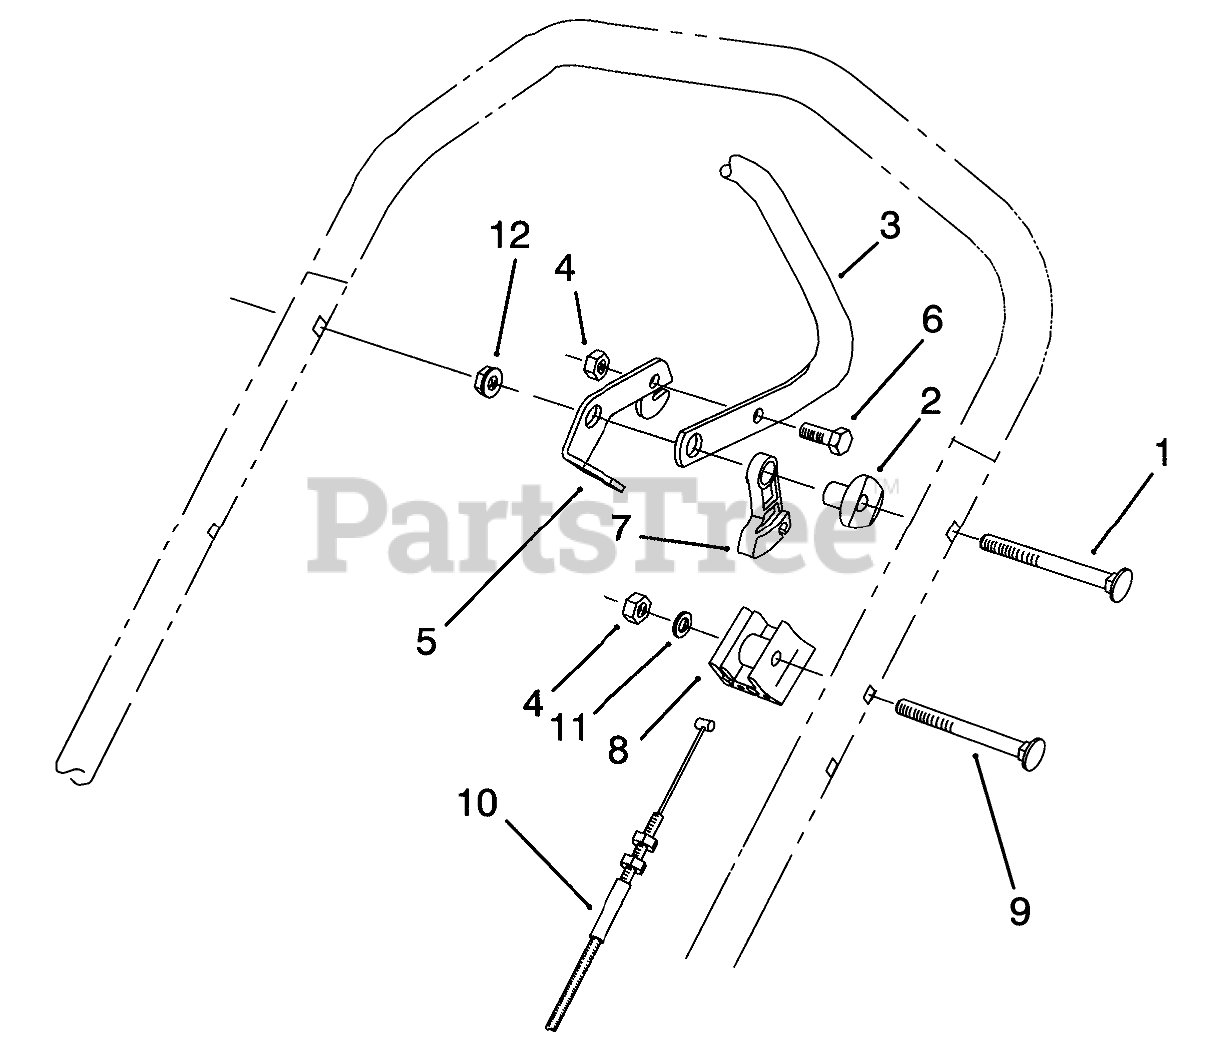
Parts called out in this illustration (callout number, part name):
1	SCREW-HANDLE
2	SPACER-SUPPORT
3	Bar-Control
4	NUT-LOCK, NI
5	LEVER-CONTROL
6	SCREW-HH
7	LEVER-TRACTION
8	SUPPORT-CABLE
9	SCREW-HANDLE
10	TRACTION CABLE
11	WASHER-FLAT
12	NUT-LOCK, NI
